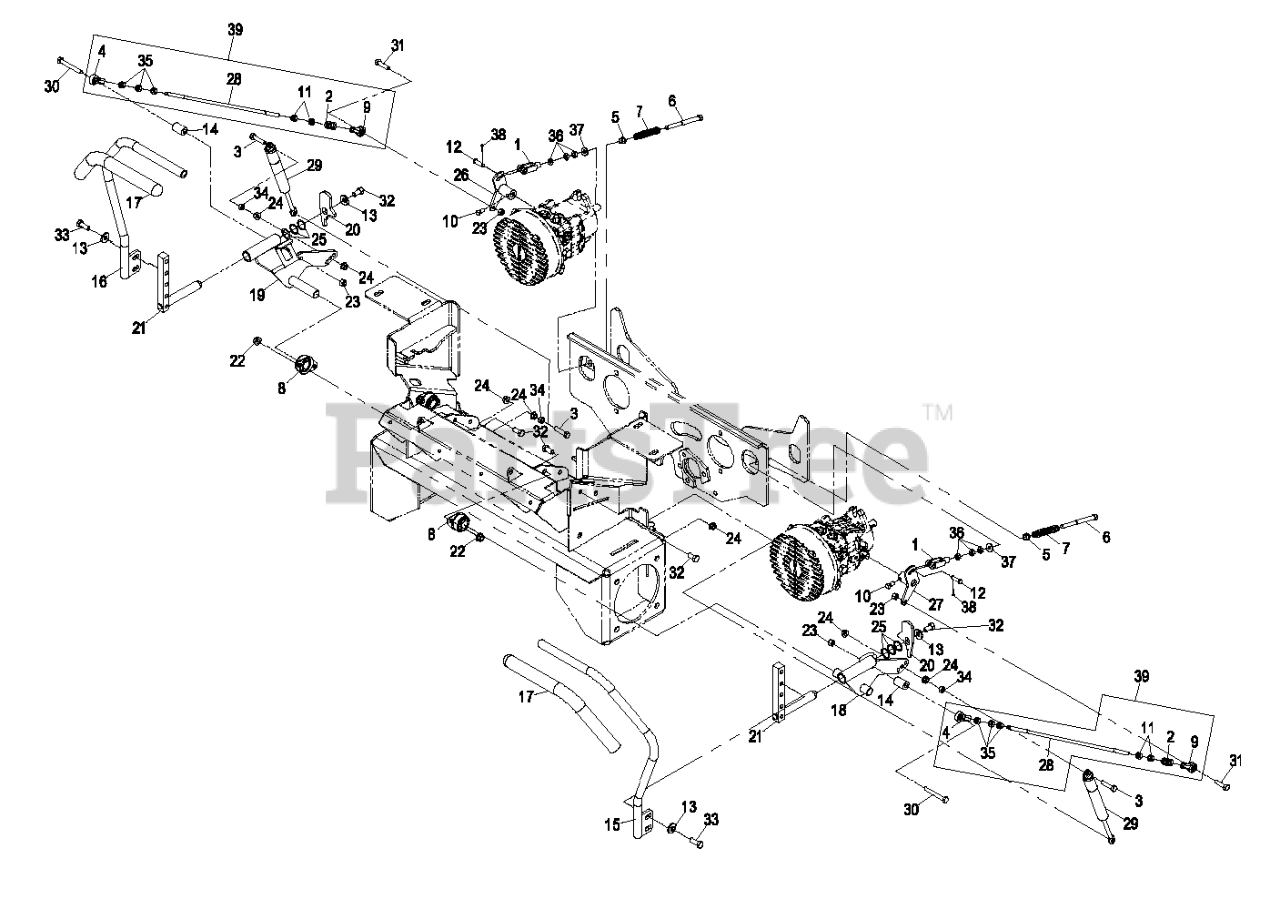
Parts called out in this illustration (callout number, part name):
1	YOKE-ADJUSTABLE
2	SPRING-COMPRESSION
3	SCREW-HH
4	BALLJOINT-RH
5	BUSHING-FLANGED
6	BOLT-RETURN, NEUTRAL
7	SPRING-RETURN, NEUTRAL
8	BEARING-FLANGE, SIDE
9	BALLJOINT-LH
10	SCREW-SET
12	PIN-CLEVIS
13	WASHER-BELLEVILLE
14	SPACER-HYDRO CONTROL, LH
15	ASM,LH LEVER/GRIP
16	ASM.RH LEVER/GRIP
17	GRIP,CONTROL LEVER
18	WLD,LH FMZ MOTION CTRL (P
19	WLD,RH FMZ MOTION CTRL(PL
20	TAB,FMZ MOTION CNTRL (PLA
21	WLD,FR CONTROL SHAFT(PLTD
22	NUT-HHF, WHIZ
23	NUT-LOCK, NI
26	WLD,PJ PUMP CONTROL RH
26	WLD,PR PUMP CTRL RH
27	WLD,PJ PUMP CONTROL LH
27	WLD,PR PUMP CTRL LH
28	ROD,TRACKING FMZ (PLTD)
28	LINK,TRACKING ROD FMZ (PL
29	DAMPER-CONTROL, MOTION
30	SCREW-HH
31	SCREW-HH
32	SCREW-HH
33	SCREW-HH
34	NUT-HEX
35	NUT-HEX
36	NUT-JAM
37	WASHER-FLAT
38	PIN-COTTER
39	ASM,FMZ PJ TRACKING ROD
39	ASM,FMZ PR TRACKING ROD
